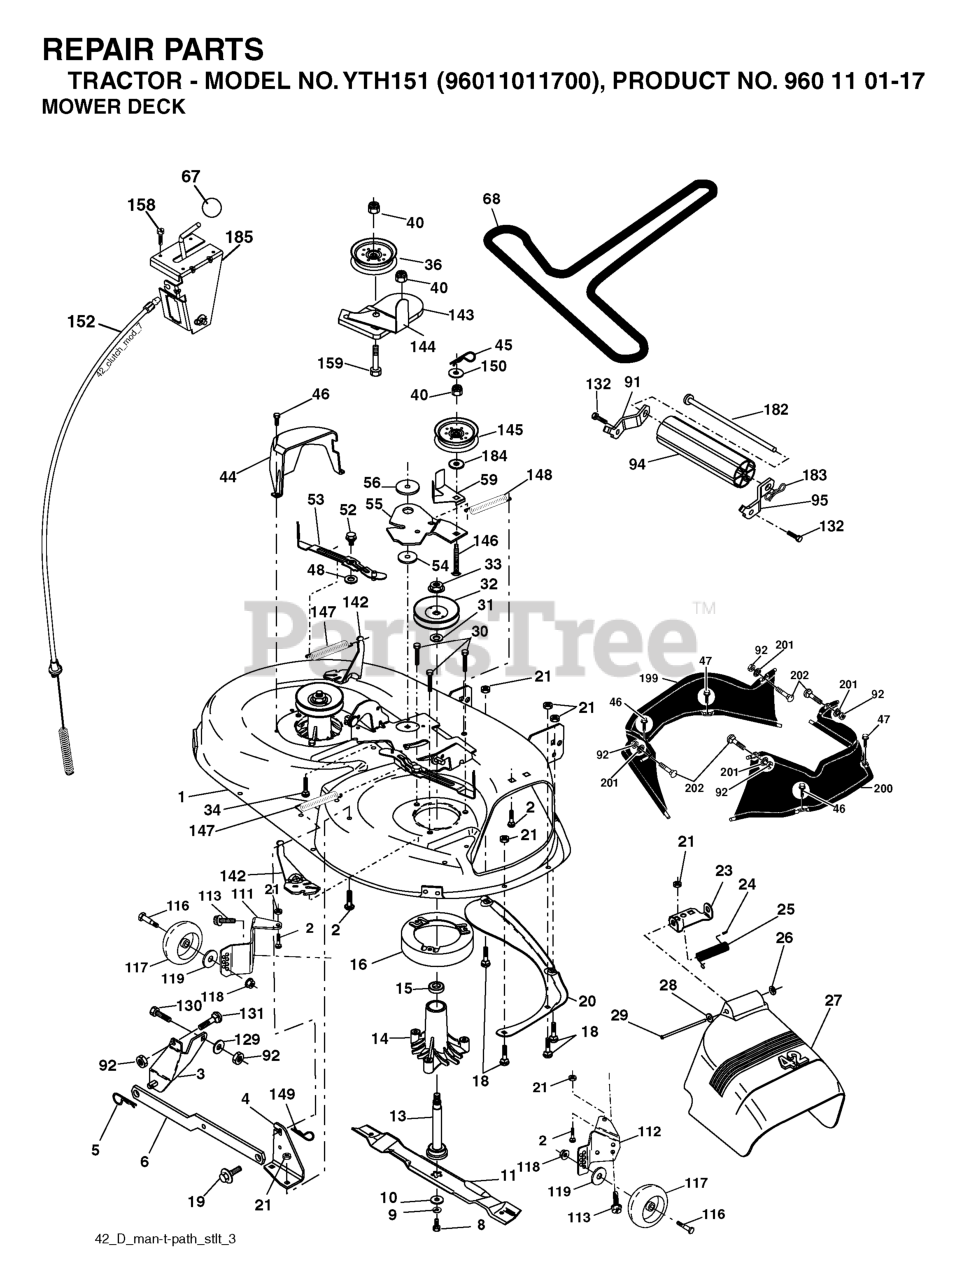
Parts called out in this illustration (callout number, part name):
1	42" DECK KIT
2	RP BOLT 5/16-18 X3/4 ZN/YEL GR
3	BRKT ASM SWAY BAR
4	BRACKET SWAY BAR 42" DECK
5	RETAINER-SPRNG RB
6	BAR SWAY DECK
8	BOLT.WASHER.ASM.7/16-2
10	WASHER.BLADE
11	42" HI-LIFT BLADE
13	SHAFT ASM VENT
14	HOUSING.MANDREL.VENTED (MACHD)
16	STRIPPER.MANDREL.ROUND.BLACK
18	BOLT
19	BOLT SHD 5/16-18
20	BAFFLE.VORTEX
21	LOCKNUT
23	BRKT, DEFL. MOWER
24	CAP-SLEEVE LT
25	SPRING TORSION
26	NUT PUSH M
27	SHIELD ASM.DFLCTR MOWER 42"BLK
28	Washer 11/32 x 5/8 x 16 Ga SD
29	ROD.HINGE
30	SCREW, WASHER HEAD
31	WASHER.SPACER.MANDREL
32	PULLEY/MANDREL
33	NUT, FLG TOPLOCK 9/16"
34	BOLT.3/8-16X1.50
36	FLAT IDLER PULLEY
40	NUT LOCK FLG 3/8-16 UNC
44	GUARD MANDREL LH BLACK
45	RETAINER M
46	SCREW.1/4-20X5/8
51	BOLT D
52	BOLT.SHOULDER.5/16-18
53	ARM BRAKE ASSY
55	ARM IDLER 42" MOWER LT/YT
56	SPACER.RETAINER.MOWER
59	GUARD, BELT
67	BATTERY TRAY T
91	BRACKET ASM NOSEROLLER LH
92	NUT
94	NOSE ROLLER
95	BRACKET ASM NOSEROLLER RH
111	BRACKET, WHEEL
112	BRACKET, WHEEL
113	BOLT.5/16HEX.WHS.HD
116	BOLT M
117	WHEEL.GAGE.HALF.SPOKED
118	LOCKNUT
119	WASHER.5/16.FLAT.STE.STD.
129	WASHER
131	BOLT D
132	SCREW, 3/8-16X3/4
142	ANCHOR SPRING BRAKE MOWER
143	BRACKET, ARM IDLER
144	DNO KEEPER.BELT.42".CLUTCH.CBL
145	PULLEY
146	BOLT, CARRIAGE IDLER BLACK
148	IDLER RETURN SPRING
149	SPRING.RETAINER.YELLOW.ZINC
152	CABLE.CLUTCH.42"
158	SCREW
182	ROD ROLLER NOSE STANDARD
183	PIN.COTTER.7/16.BOW TI.
184	WASHER
185	HEAD ASM. CABLE CLUTCH
201	PUSH.NUT.ROUND.3/8.DIAM
202	BOLT D
